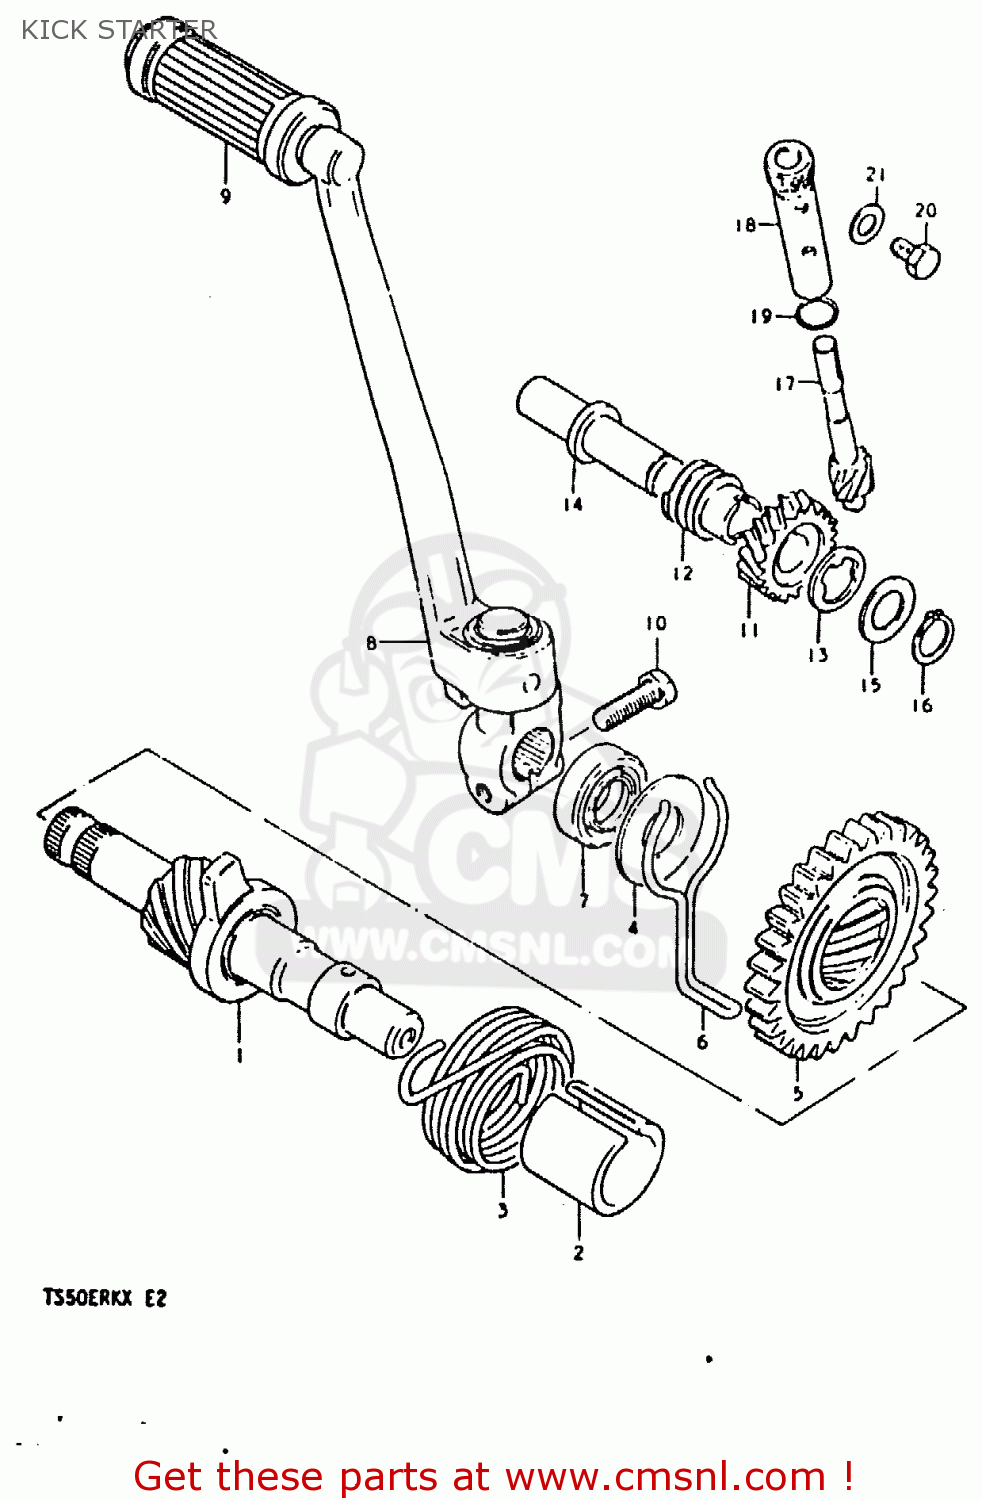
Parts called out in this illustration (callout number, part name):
1	SHAFT,KICK STARTER
2	GUIDE,KICK STARTER SFT SPRING
3	SPRING
4	WASHER
5	GEAR,KICK STARTER DRIVE(NT:30)
6	RETAINER,SNAP
7	SEAL,OIL(14X24X6)
8	LEVER ASSEMBLY,KICK STARTER
9	RUBBER,KICK STARTER PEDAL
10	BOLT
11	GEAR, TACHOMETER DRIVE NO.2
12	GEAR,TACH DRIVE NO.2(NT:3)
13	RETAINER,TACH DRIVEN GEAR NO1
14	SHAFT,TACHOMETER DRIVEN GEAR
15	WASHER,THRUST
16	CIRCLIP
17	GEAR,TACHOMETER DRIVEN(NT:12)
18	SLEEVE
19	O RING(D:1.3,ID:9.6)
20	BOLT
21	GASKET(6.2X11X1).2 (NAS)
